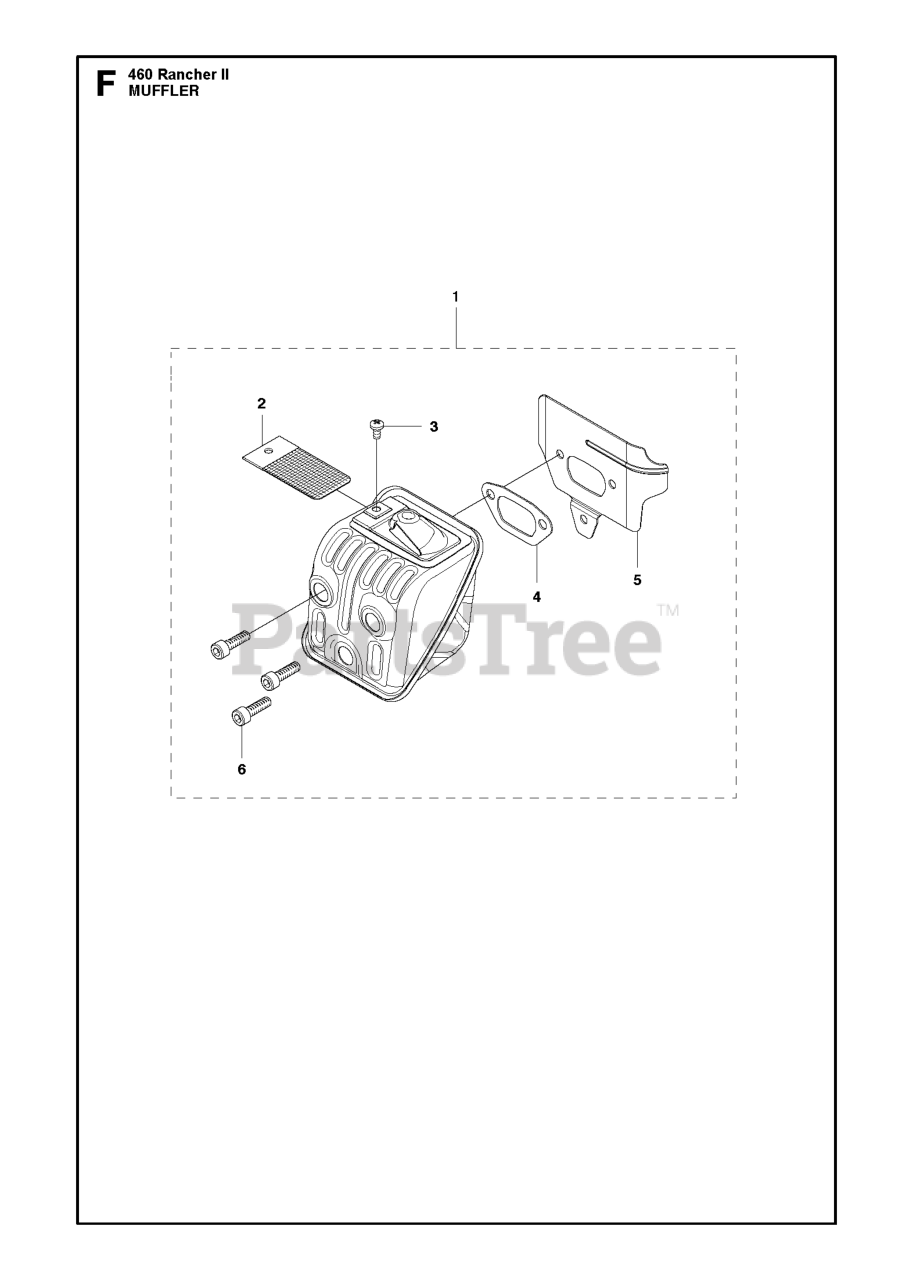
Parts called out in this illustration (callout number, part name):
1	MUFFLER KIT
2	SPARK ARRESTOR SCREEN
5	HEAT DEFLECTOR
6	SCREW MC6S 6X20
